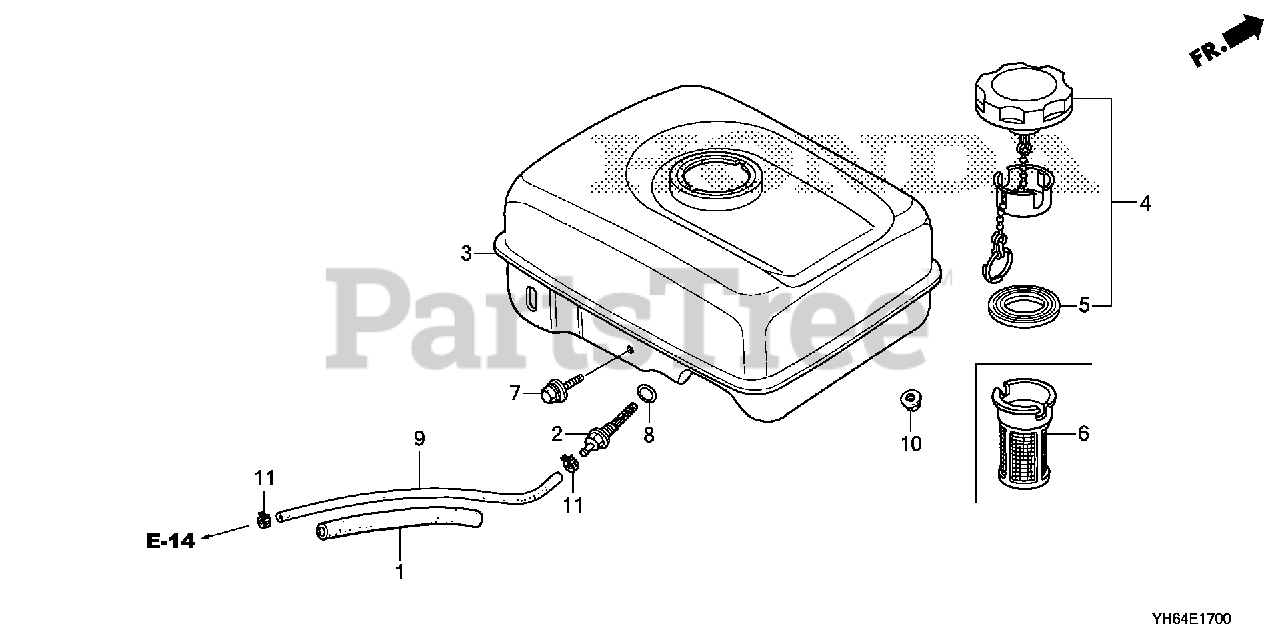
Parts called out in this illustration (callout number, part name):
1	RUBBER, SUPPORTER (107MM)
2	JOINT, FUEL TANK
3	TANK, FUEL *R280* (POWER RED)
4	CAP, FUEL FILLER
5	GASKET, FUEL FILLER CAP
5	GASKET, FUEL FILLER CAP (39X62X3) (TOUYOUSYA)
6	FILTER, FUEL
7	BOLT, FLANGE (6X29)
8	O-RING (14MM) (ARAI) Use up to Engine SN 2949254.
8	O-RING (14MM) (NOK)
10	NUT, FLANGE (6MM)
11	CLIP, TUBE (D8)
